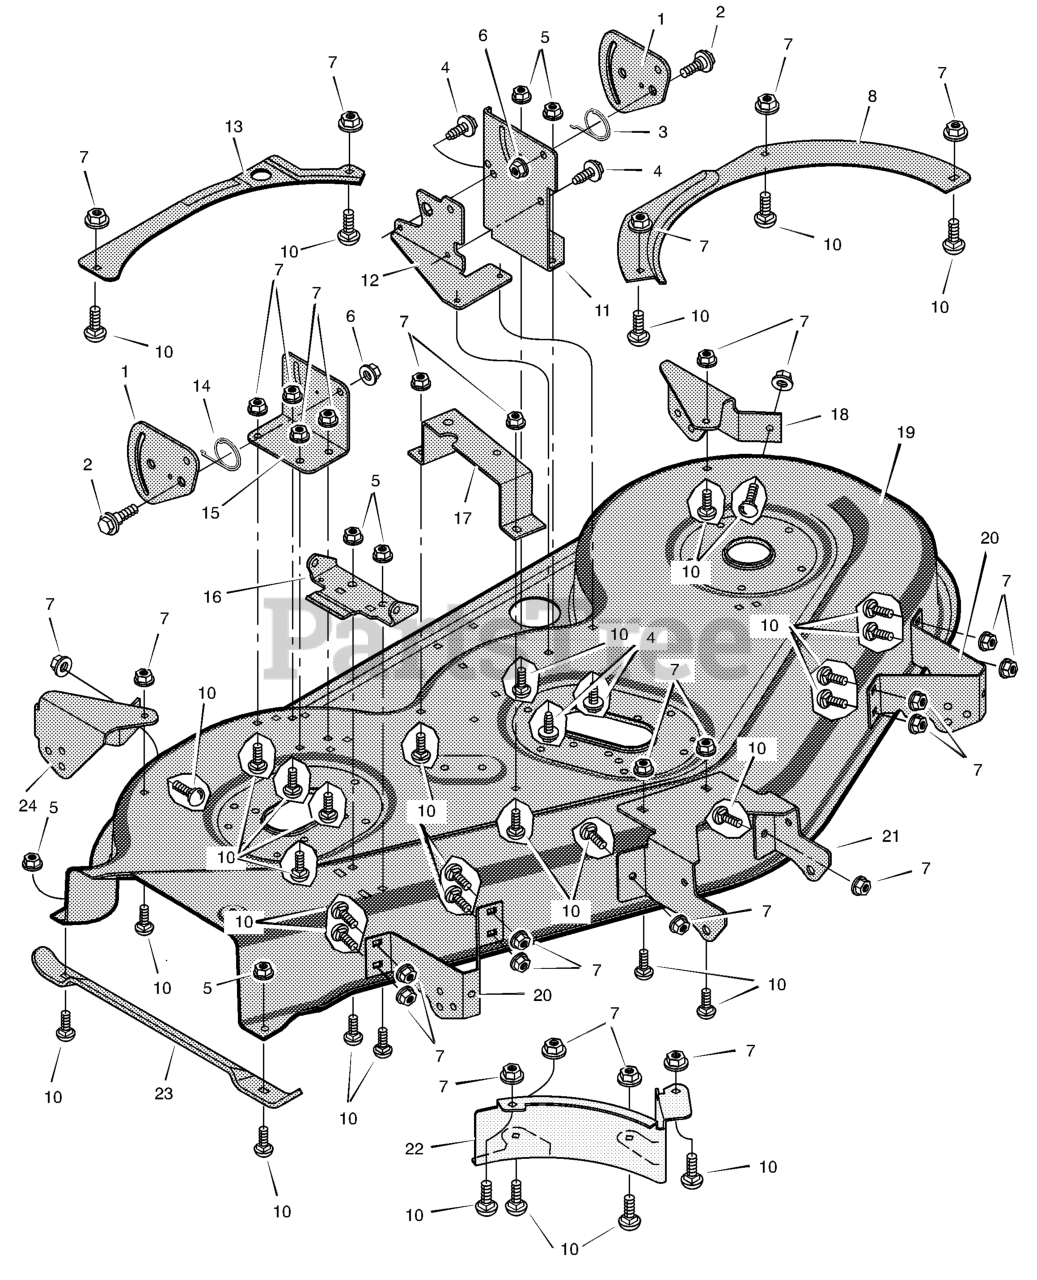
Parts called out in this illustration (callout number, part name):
1	Plate, Suspension
2	Bolt, Shoulder
3	Spring, Left Torsion
5	Nut, Flange
6	Nut, Flange
7	Nut, Flange
8	Baffle, Left
10	Bolt, Carriage
11	Bracket, Left Lifter
12	Brace, Lifter
13	Baffle, Bottom
14	Spring, Right Torsion
15	Bracket, Right Lifter
16	Bracket, Hinge
17	Bracket, Bellcrank
18	Bracket, Left Gage Wheel
19	Housing, Blade
20	Bracket, Front Gage Wheel
21	Bracket, Front Deck
22	Baffle, Right
23	Bracket, Chute Support
24	Bracket, Right Gage Wheel
